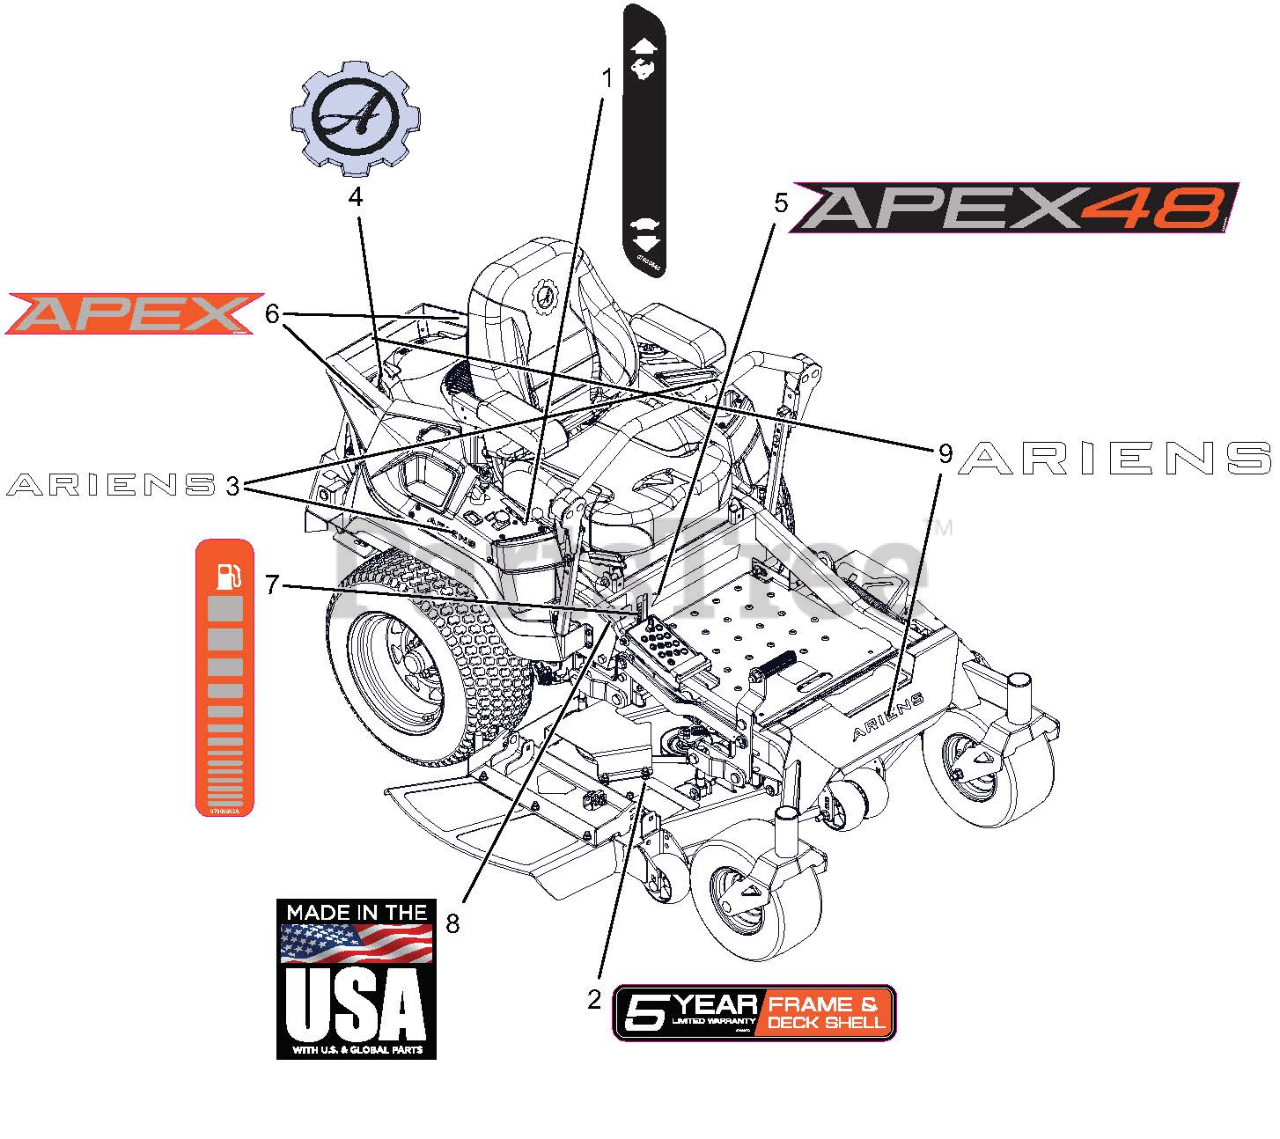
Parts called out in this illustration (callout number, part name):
1	DECAL, DASH DECAL
2	DECAL, DECK 5 YEAR-ARIENS
3	DECAL, ARIENS (6.50")
4	DECAL, ARIENS-GEAR BADGE -THK
5	DECAL, 48" APEX KICKPLATE
6	DECAL, APEX FENDER
7	DECAL, ARIENS FUEL LEVEL
8	DECAL, MADE IN USA
9	DECAL - ARIENS 9.625"
